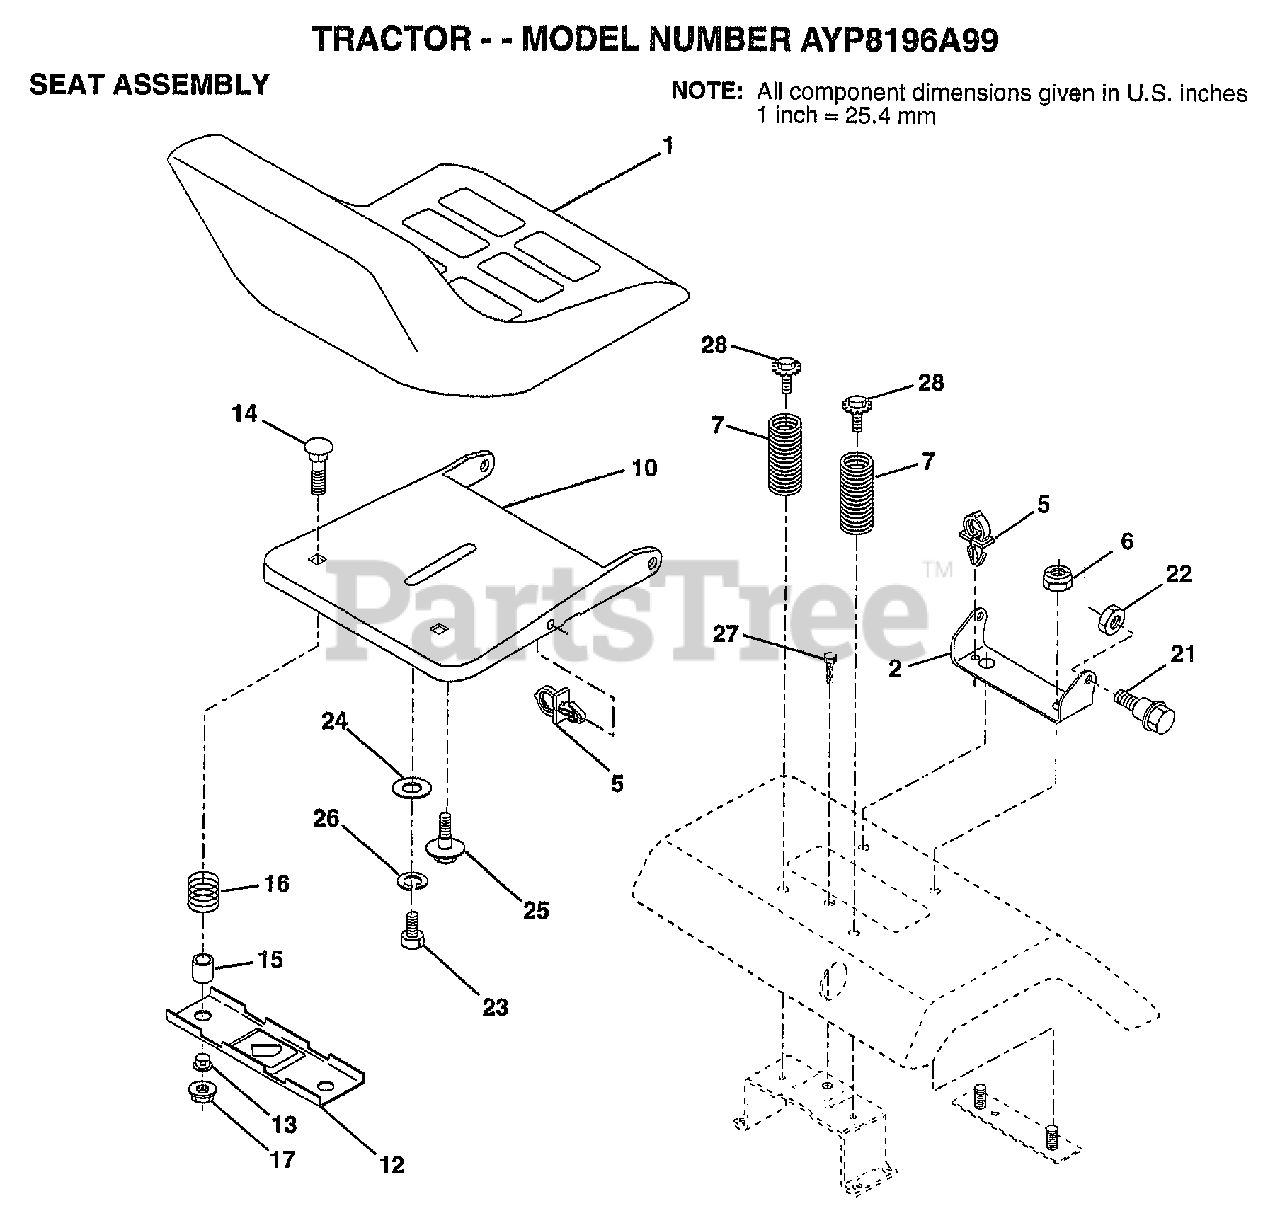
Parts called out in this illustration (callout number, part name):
1	SEAT.2400/1416.BK
2	BRACKET PVT SEAT
5	CLIP.PUSH-IN.HING
6	NUT
7	SPRING COMPRESSIO
10	PAN-SEAT
12	BRKT SWITCH
13	BUSHING
14	BOLT-RD HD SQ NK
15	SPLIT SPACER
16	SPRING
21	"BOLT,SHOULDER"
22	NUT
23	BOLT
24	WASHER
25	"BOLT,SHOULDER"
26	LOCKWASHER
27	SCREW LT
28	BOLT.5/16-18.UNC
